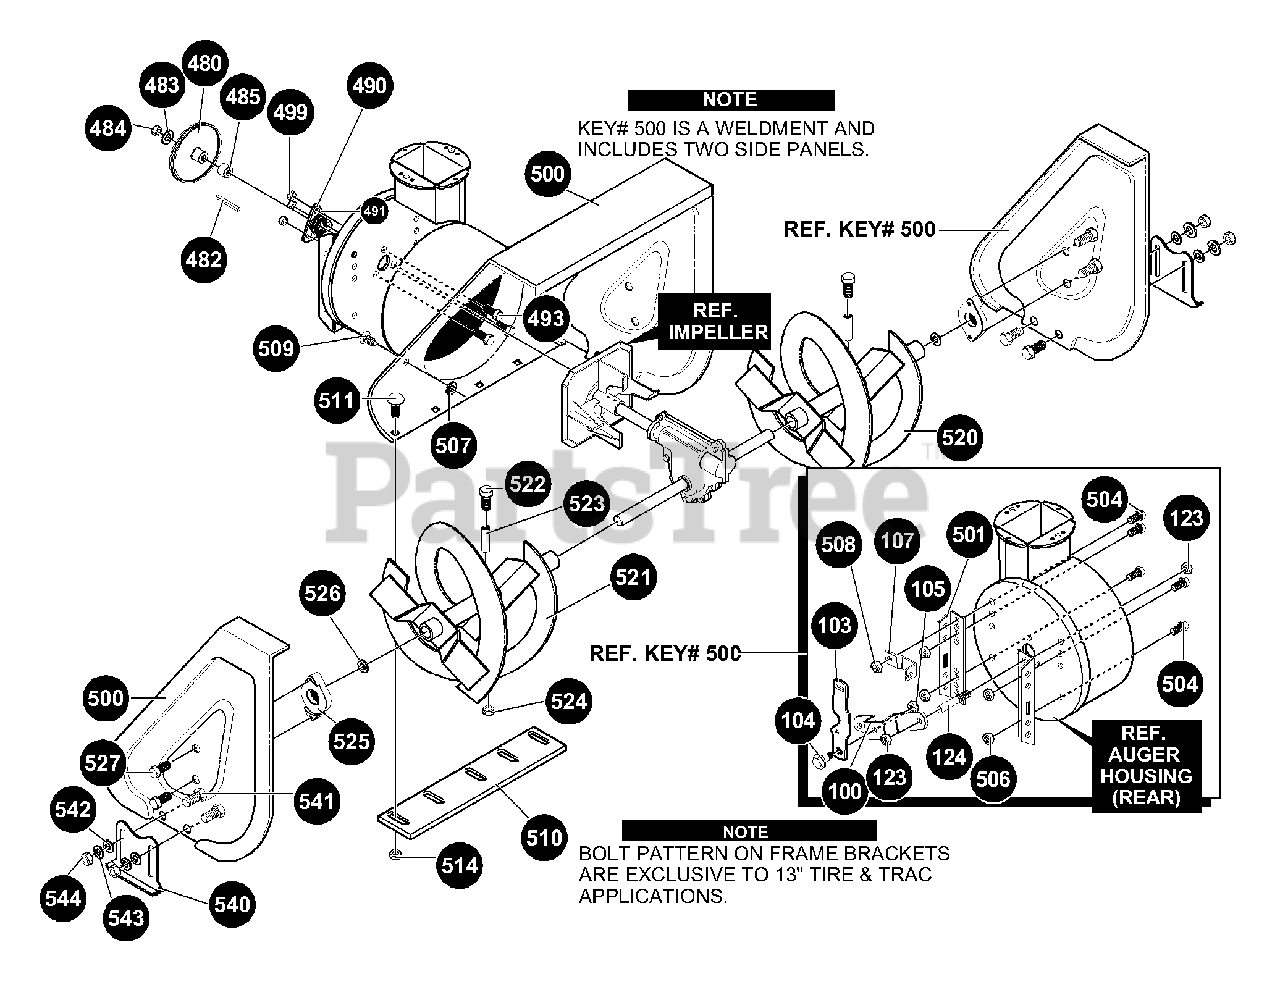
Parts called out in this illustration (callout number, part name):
100	PLATE, CLUTCH ARM MT.
103	BRACKET, IDLER
104	SH. BOLT 3/8-16
105	NUT, 3/8-16 RGHXCTRLK
107	BRACKET, CABLE MT.
123	NUT, 3/8-16 RGHXCTRLK
124	STUD, BRAKE ARM
125	WASHER, REGSPTLK
480	PULLEY, V4L 8.40 OD
482	KEY, SQUARE
483	FLATWASHER .53 X1.00X.063
484	NUT, 1/2-20
485	SPACER, SLEEVE
490	RETAINER, BALL
491	BEARING, BALL
493	SCREW, 5/16-18X .75
499	NUT, 5/16-18
500	HSNG, ASSY
501	BRKT, MOUNT
504	SCREW, 3/8-16X .75
506	NUT, 3/8-16
507	FLATWASHER
508	NUT, 3/8-16
510	BLADE, SCRAPER
511	BOLT, 5/16-18X.75
514	NUT, 5/16-18 HXWDFLLK
520	AUGER, ASSY LH
521	AUGER, ASSY RH
522	SCREW, 1/4-20X1.75
523	SPACER, SLEEVE
524	NUT, 1/4-20
525	AUGER SHAFT BEARING
526	FLATWASHER 1.005X1.31X.035
527	SCREW, 5/16-18X .75
540	SKID, HEIGHT ADJUST
541	BOLT, 5/16-18X .75
542	FLATWASHER .344X .69X.065
543	WASHER, .328X.60X.09
544	NUT, 5/16-18 REGHEX
